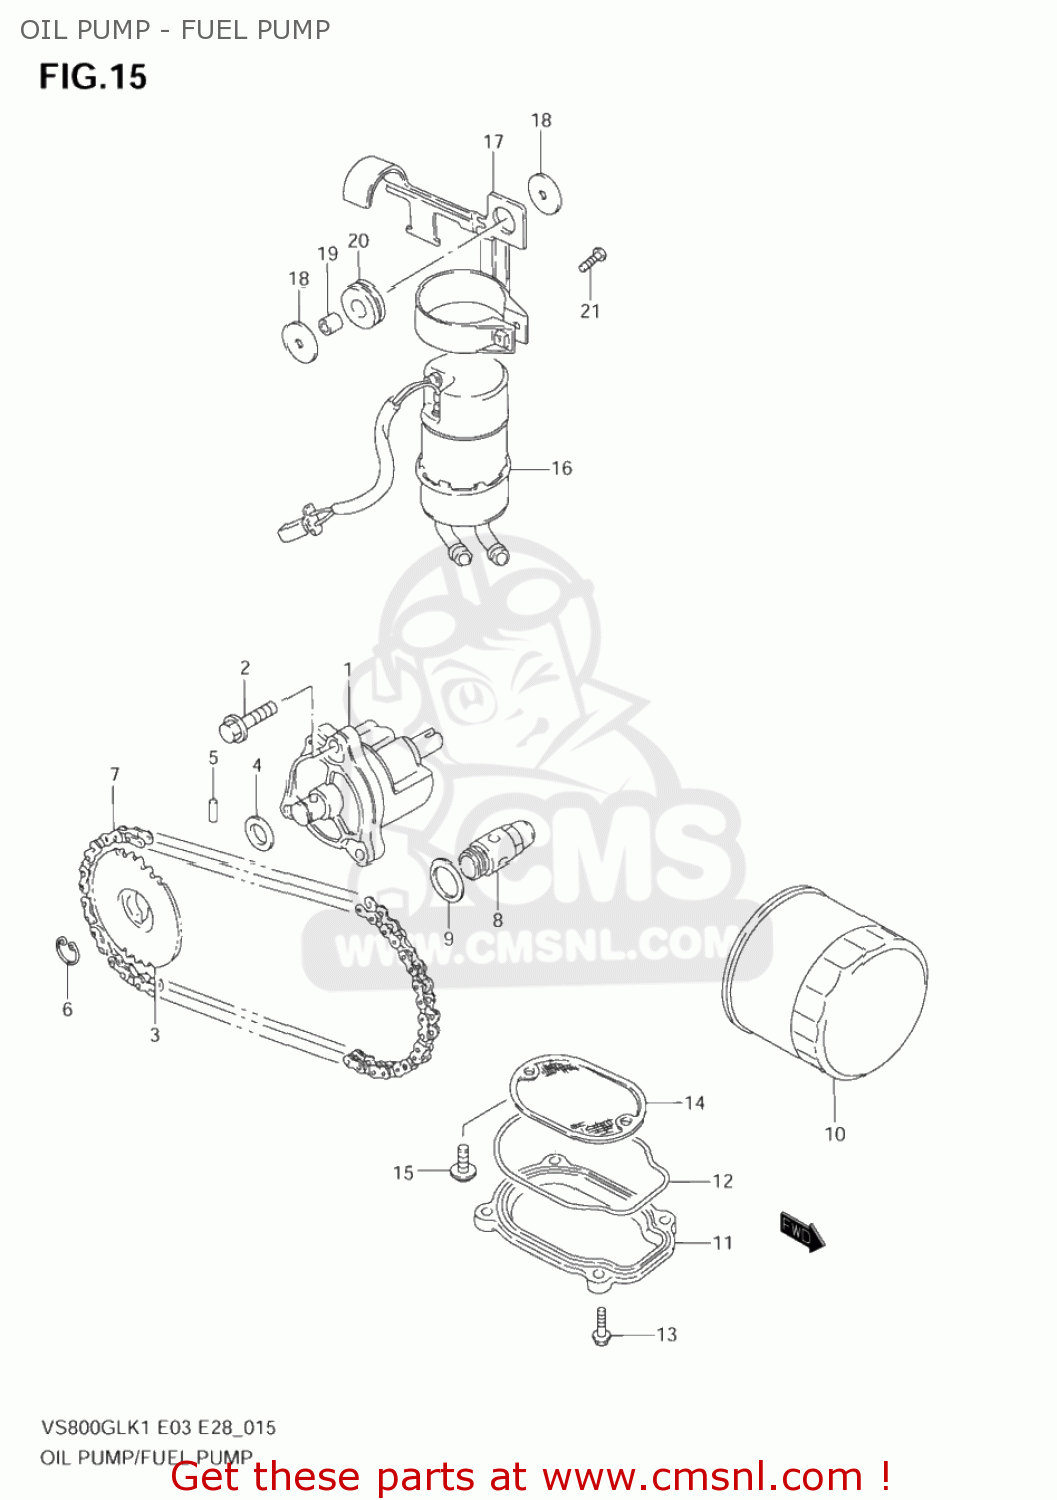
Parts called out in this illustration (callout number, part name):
1	PUMP ASSY,ENGINE OIL
2	BOLT
3	SPROCKET,OIL PUMP DRIVEN
4	SHIM(12X20X0.5)
5	PIN(5X18)
6	CIRCLIP,12 MM
7	CHAIN,OIL PUMP DRIVE
8	VALVE ASSY,OIL RELIEF
9	GASKET(16X22X2) (NAS)
10	FILTER ASSY,EN
11	CAP,OIL STRAINER
12	O RING,OIL STRAINER CAP
13	BOLT
14	STRAINER,ENGINE OIL
15	SCREW
16	PUMP ASSY,FUEL
17	BRACKET,FUEL PUMP
18	WASHER
19	SPACER(6.5X10.5X6.5)
20	CUSHION
21	SCREW
